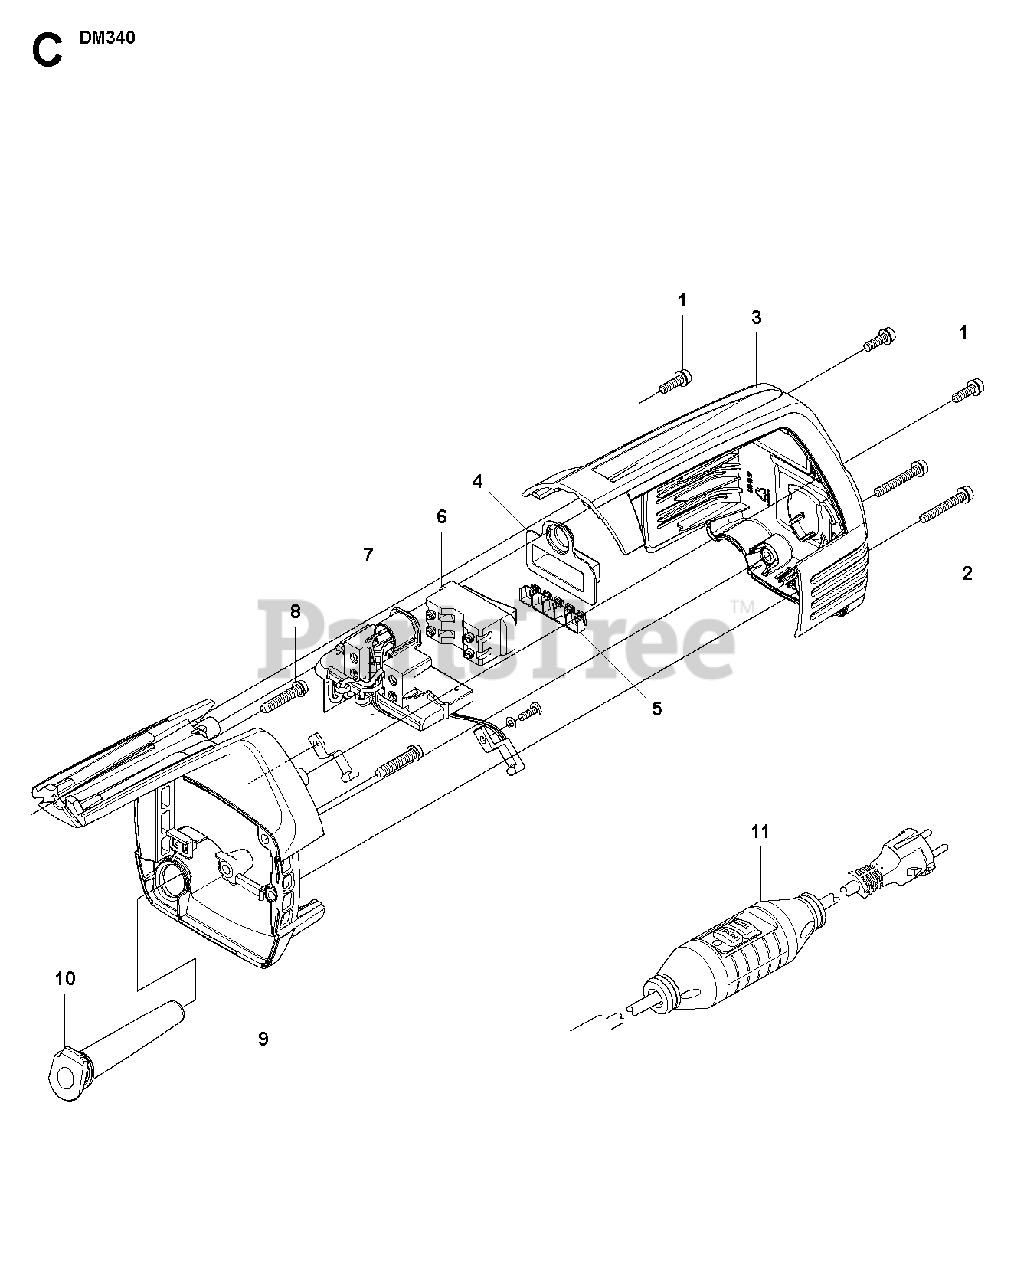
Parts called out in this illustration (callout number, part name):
1	SCREW IHSCFM
2	SCREW IHSCFM
11A	CABLE230V incl PRCD 10mV, EU
11B	CABLE230V incl PRCD 10mV, AU
